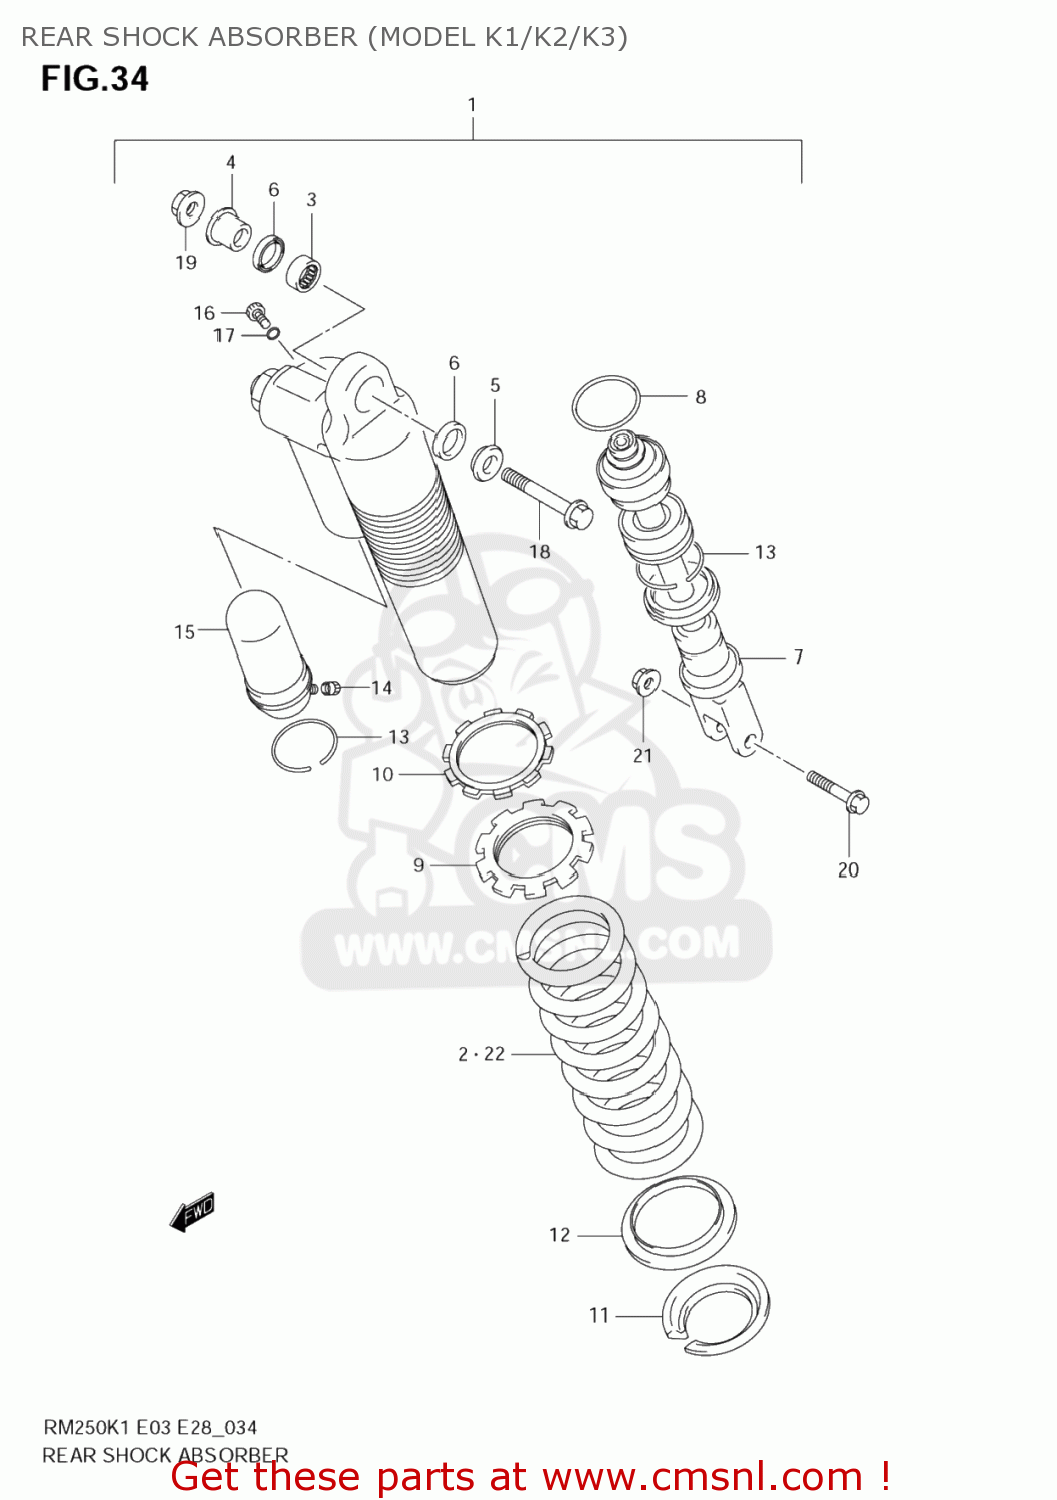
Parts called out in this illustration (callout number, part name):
1	ABSORBER ASSY,RR SHOCK
2	SPRING,REAR
3	BEARING(16X22X12)
4	SPACER,UPPER BRG,R
5	SPACER,UPPER BRG,L
6	SEAL,OIL(16X22X2.5)
7	ROD,PISTON
8	O RING
9	GUIDE,SPRING
10	NUT
11	GUIDE,SPRING
12	GUIDE,SPRING
13	RING,STOPPER
14	CAP,VALVE AIR
15	BLADDER
16	BOLT
17	O RING
18	BOLT(10X60)
19	NUT
20	BOLT(10X44.5)
21	NUT
22	SPRING (SOFT,K=4.8)
